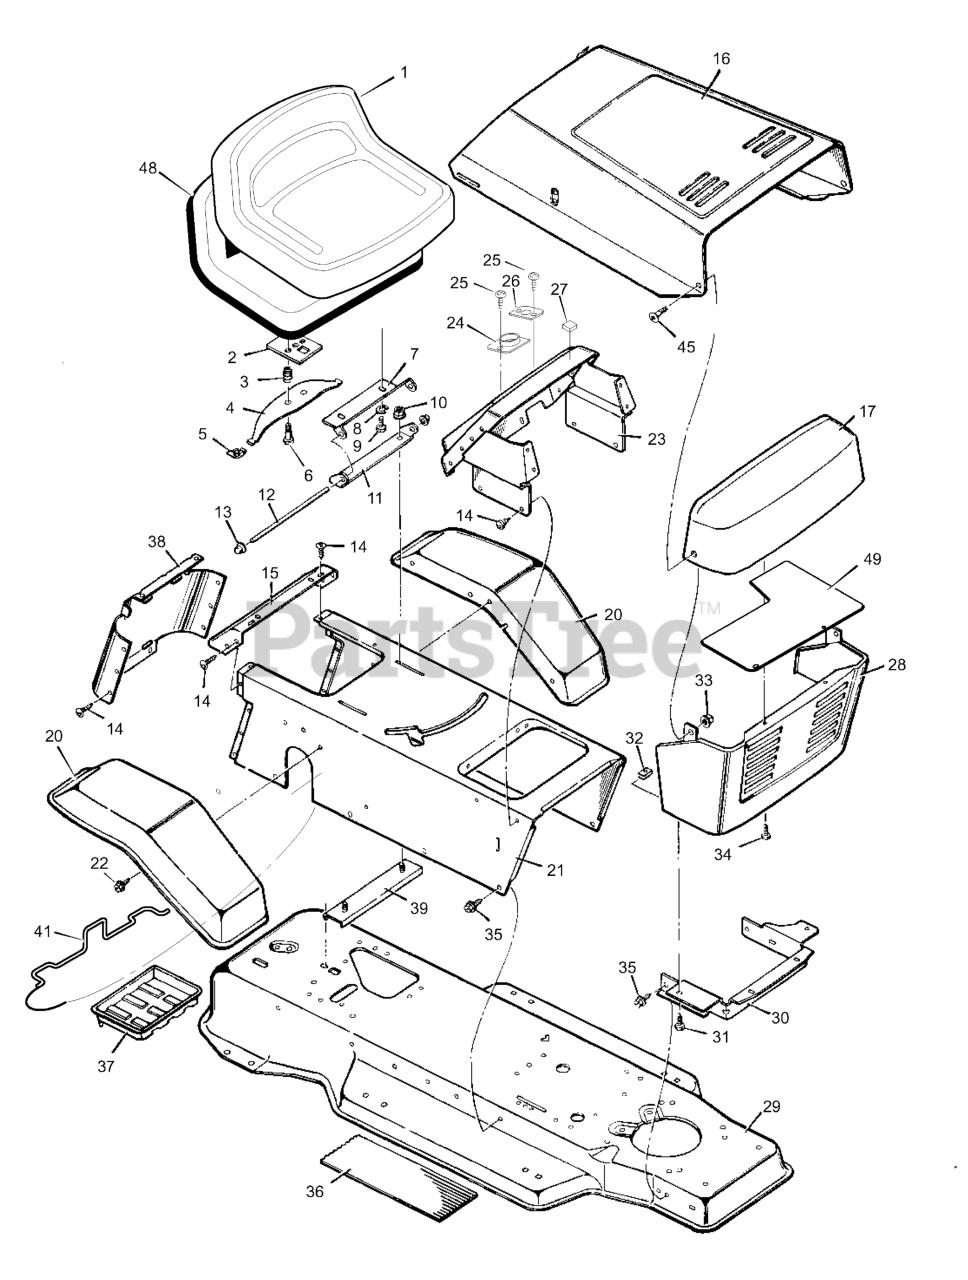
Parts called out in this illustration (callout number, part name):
2	Plate Assembly, Switch
3	Spring, Compression
4	Spring, Seat
5	Glide, Spring
6	Bolt, Shoulder
7	Support, Seat
8	Lockwasher
9	Bolt, Hex
10	Locknut, Flange
11	Bracket, Pivot
12	Rod, Pivot
13	Cap, Push On
14	Screw, Tap
15	Fender, Apron
17	Grille, Upper
21	Console Assembly
23	Dash Panel
24	Bearing, Steering
26	Bearing
27	Bumper
28	Grill, Lower
29	Frame Assembly
30	Support, Grill
33	Locknut, Flange
34	Fastener, Plastic
37	Tray, Battery
38	Cap, Console
39	Channel Assembly
41	Clamp, Battery
45	Bolt, Shoulder
48	Pan, Seat (with foam)
49	Shield, Heat
